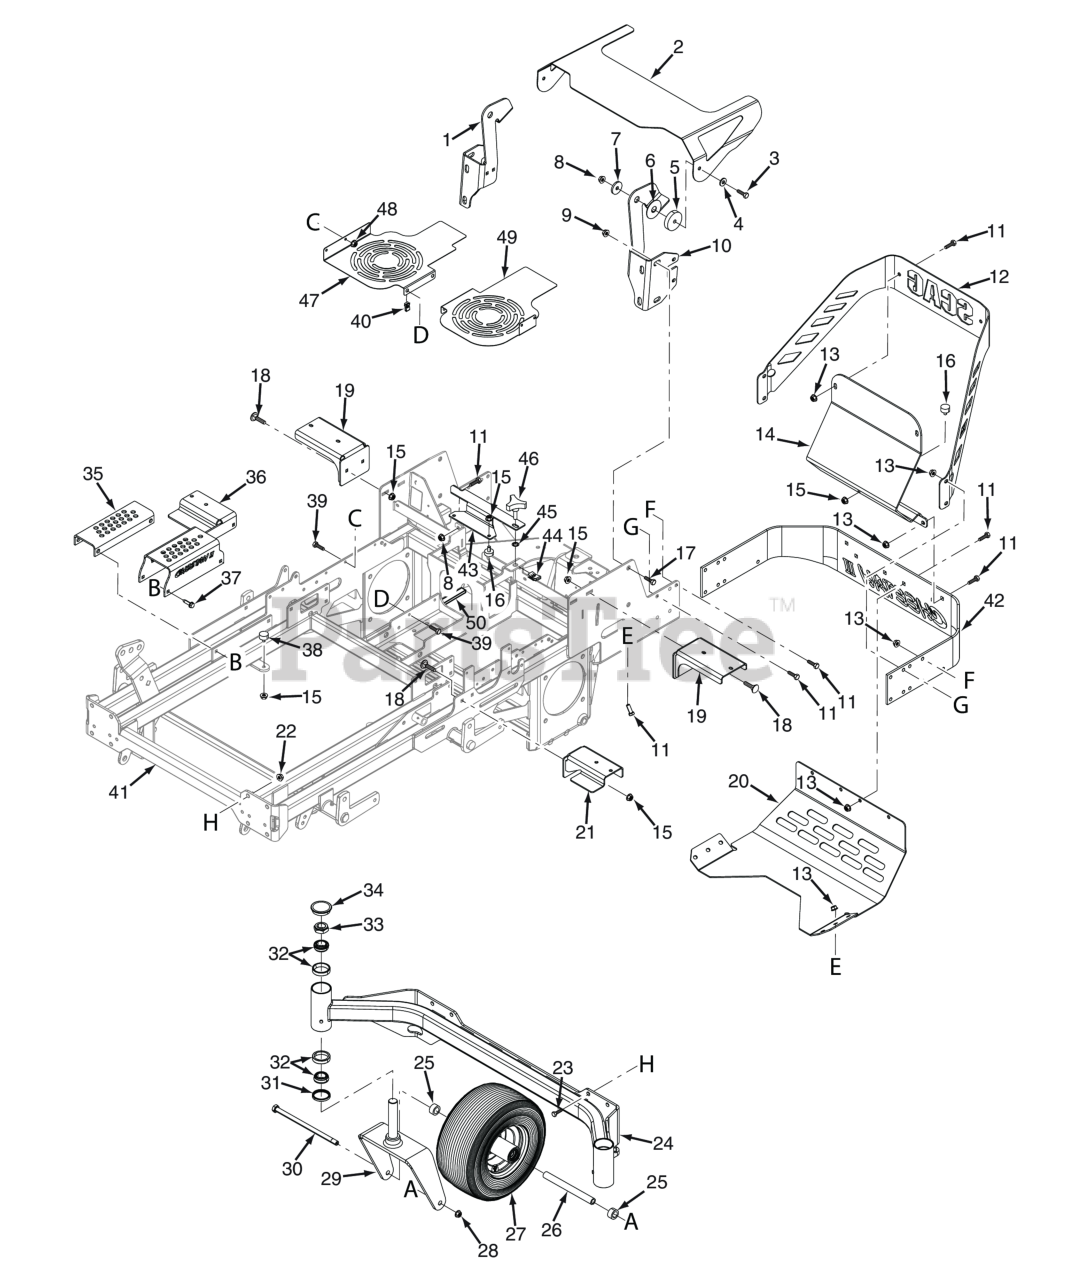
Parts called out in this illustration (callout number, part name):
1	ROPS Mount, RH, 29CV-EFI
2	Hood, SCZII
3	Bolt, Hex Head 3/8-16 x 1-3/4" (Kohler EFI)
5	Flatwasher, 3/8" Special (.391 x .938 x .105)
6	Spacer, Hood
7	Disc, Anti-Friction
8	Flatwasher, 3/8-.406 x 1-1-1/2 x 7 Gauge
9	HEX NUT, ELASTIC STOP LOCK, 3/8-16
10	Nut, Elastic Stop 1/2-13, (STT-52 & STTII-52)
11	ROPS Mount, LH, 29CV-EFI
12	Bolt, Hex Head, 3/8-16 x 1 Gr. 5
13	NUT, 3/8-16 SERRATED FLANGE HEX HEAD
14	Engine Cover, Rear (Scag Gold)
15	Nut, Serrated Flange 5/16-18 (Right Front Engine Mounting, Briggs and Kohler Only)
16	Bumper, Rubber 5/16-18 x 5/8"
17	Bolt, Hex Head 1/2-13 x 1-1/4"
18	Bolt, 5/16-18 x .75 RHSN Carriage
19	Mounting Bracket, Fuel Tank Rear
20	Skid Plate, Rear (Scag Gold)
21	Mounting Bracket, Fuel Tank Front
22	Nut, 7/16-14 Flange Elastic Stop
23	BOLT, HEX HEAD, 7/16-14 X 1-1/4
24	Caster Support 61V (Scag Gold)
25	Spacer, Caster Wheel
26	Sleeve, Caster Wheel (61V, 72A/VS)
27	Wheel Assy, 61V, 72V (Incl. 20, 54, 55)
28	HEX LOCKNUT, ELASTIC STOP, 1/2-13
29	Yoke Weldment
30	Bolt, Hex Head 1/2-13 x 9-1/2" (61V & 72A/VS)
31	Seal, 2.00" O.D. x 1.625" Bore
32	Bearing Set
33	Nut, Elastic Stop 1.0"-14
34	Cap, Grease
35	Adjustment Bracket, Lower Cut Height
36	Bracket, Upper Cutting Height
37	Bolt, Hex Wshr Head 5/16-18 x 1-1/4"
38	Bumper, Rubber
39	Bolt, Serrated Flange Hex Head 1/4 x 20 x 3/4"
40	Bolt, Hex Head 3/8-16 x 1"
41	Frame w/ Decals (Scag Gold)
42	Bumper, Rear (Scag Gold)
43	Cover, Battery Box (Scag Gold)
44	U-Nut, 3/8-16 (short)
45	Nut, Push-On - 3/8" Dia.
46	Knob, w/stud 3/8-16 x 1-1/4"
47	Fan Cover, RH (Scag Gold)
48	NUT, 1/4-20 SERRATED FLANGE HEX HEAD
49	Fan Cover, LH (Scag Gold)
50	PAD, BATTERY SUPPORT
